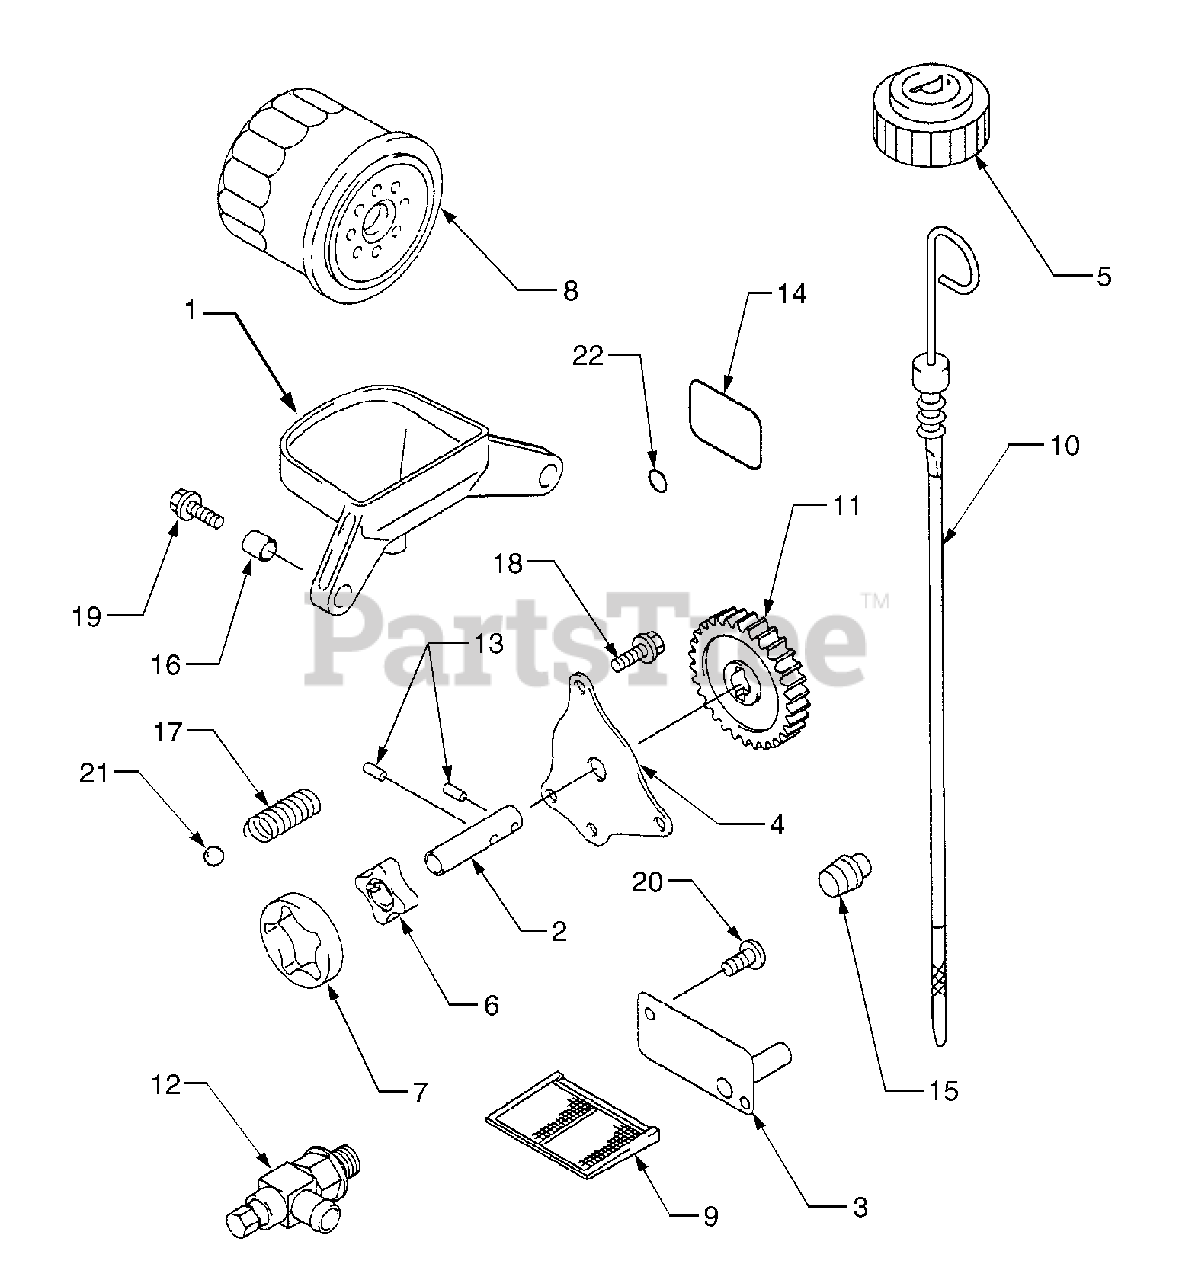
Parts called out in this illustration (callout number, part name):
1	Receiver, Oil
2	Shaft, Oil Pump
4	Cover, Oil Pump
5	Cap, Oil Filler
6	Rotor, Pump Inner
7	Rotor, Pump Outer
8	Filter, Oil
9	Screen, Oil Filter
10	Dipstick, Engine Oil
12	Fitting, Oil Drain
16	Collar, 8.2 x 10 x 10
17	Spring, Relief Valve
18	Bolt, Flanged
19	Bolt, Flanged
21	Ball, Steel
